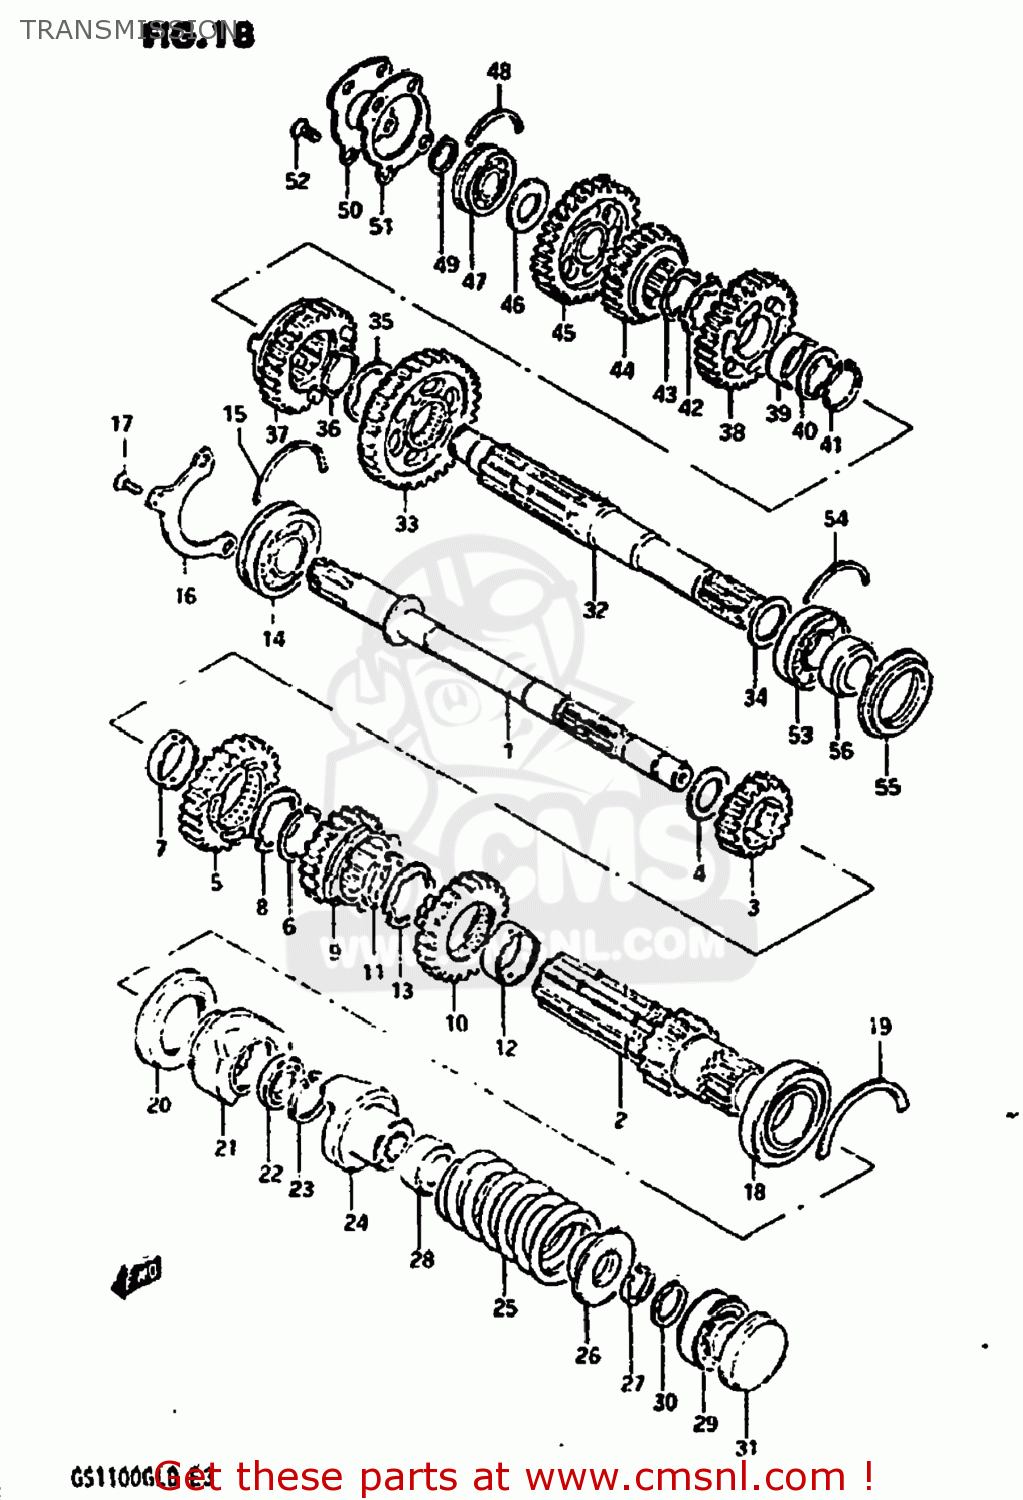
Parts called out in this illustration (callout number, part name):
1	SHAFT,COUNTER
2	SHAFT,OUTER COUNTER
3	GEAR,SECOND DRIVE
4	WASHER (21X35X2)
5	GEAR,5TH DRIVE(NT:26)
6	RING,SNAP
7	SPACER,DRIVE GEAR
8	LOCK WASHER,5TH DR GEAR SPACER
9	GEAR,THIRD DRIVE
10	GEAR,FOURTH DRIVE
11	RING,SNAP
12	SPACER,DRIVE GEAR
13	LOCK WASHER,5TH DR GEAR SPACER
14	BEARING(25X62X17)
15	C-RING
16	RETAINER,CNTR SHAFT BEARING
17	SCREW
18	BALL BEARING 32X58X13
19	C-RING
20	SEAL,OIL(40X58X7)
21	DOG,OUTPUT CAM
22	SEAL,OIL(20.6X31X6)
23	CIRCLIP
24	DOG,INPUT CAM
25	SPRING
26	STOPPER,CAM DOG SLIDING
27	STOPPER,CAM DOG
28	GUIDE,CAM DOG SPRING
29	BEARING
30	SPACER (17X21X3.5)
31	PLUG
32	SHAFT,DRIVE
33	GEAR,FIRST DRIVEN
34	WASHER, LH
35	WASHER,LOCK
36	CIRCLIP
37	GEAR,FOURTH DRIVEN
38	GEAR,THIRD DRIVEN
39	BUSH,3RD DRIVEN GEAR
40	WASHER,LOCK
41	CIRCLIP
42	WASHER
43	WASHER,LOCK
44	GEAR,FIFTH DRIVEN
45	GEAR,SECOND DRIVEN
46	WASHER
47	BEARING(20X47X14)
48	C RING
49	CIRCLIP
50	PLATE,DRIVESHAFT
51	GASKET,DRIVESHAFT PLATE (MCA)
52	SCREW
53	BEARING
54	C RING
55	SEAL,OIL(35X52X6)
56	SPACER,DRIVESHAFT,LEFT
